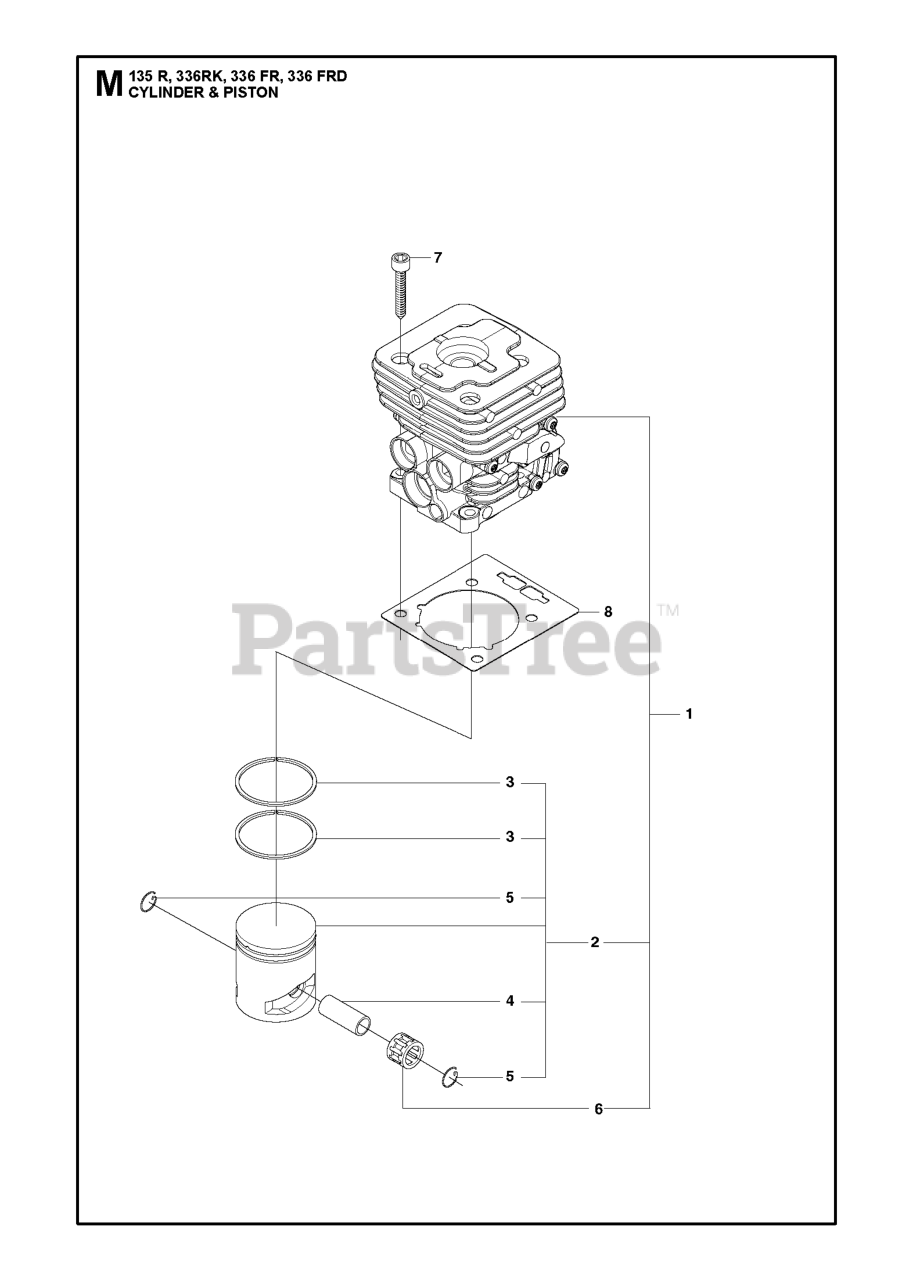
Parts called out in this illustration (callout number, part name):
1	%CYLINDER CPL
2	PISTON ASSY
3	PISTON RING
4	PISTON BOLT
5	LOCKING RING
6	SUPPORT BUSHING
7	SCREW MC6S 5X25
8	GASKET CYLINDER
